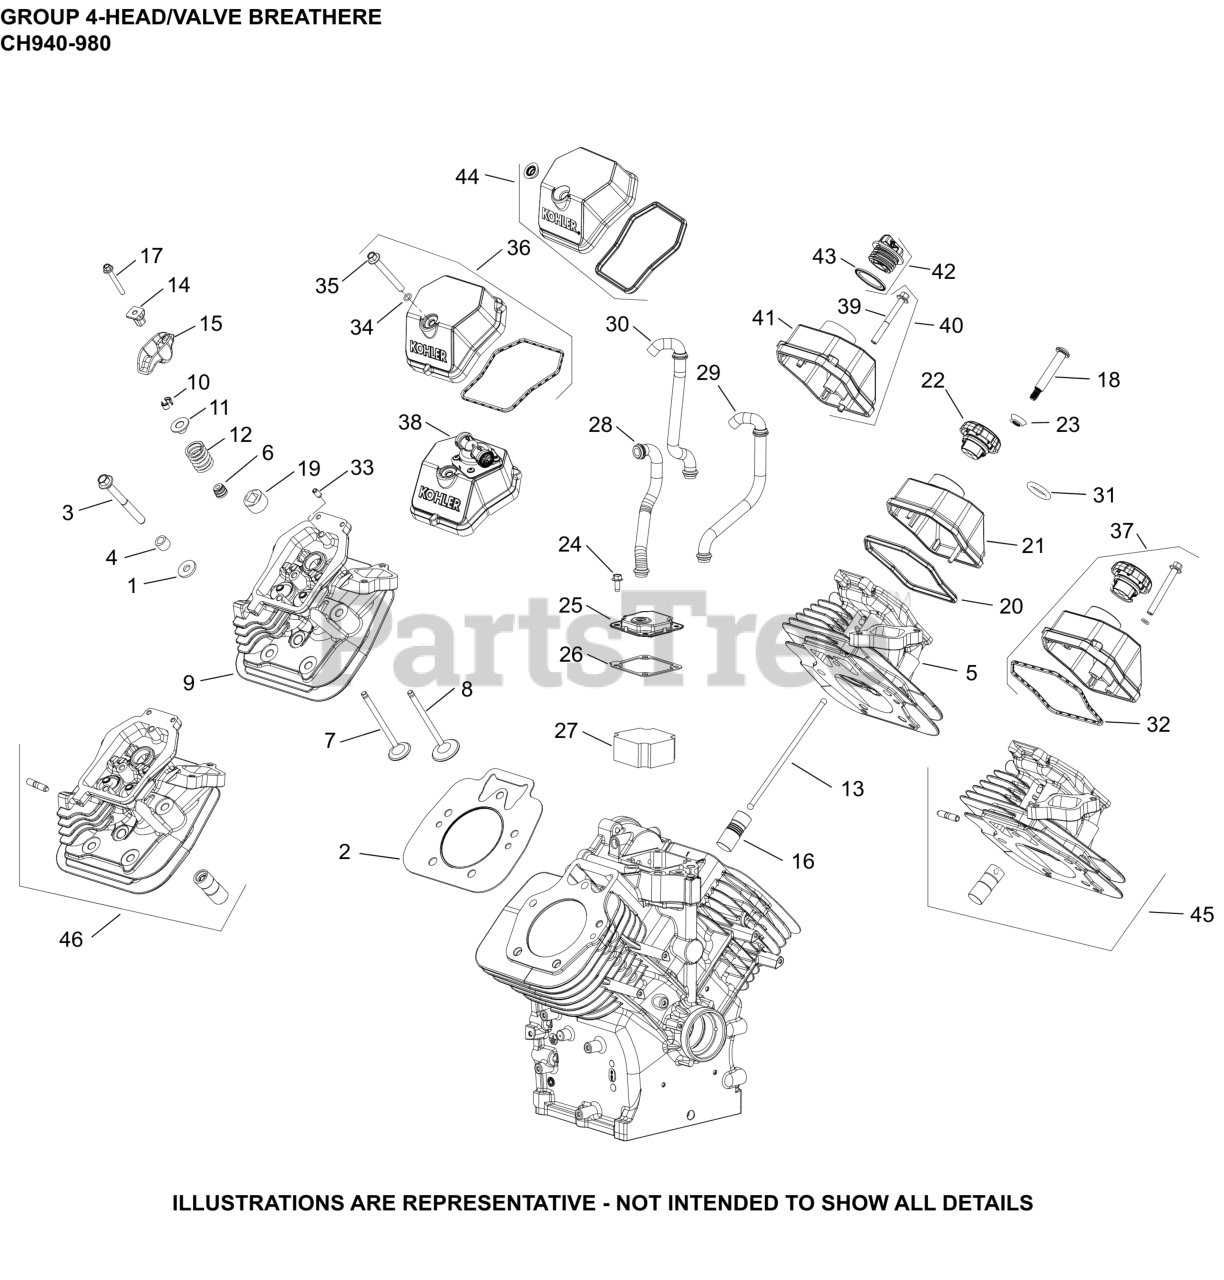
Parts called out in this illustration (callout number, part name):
1	WASHER, FLAT 13/32"
2	KIT, CYLINDER HEAD GASKET
3	SCREW, FLG M10X1.5X90
6	SEAL, VALVE BAND
7	VALVE, EXHAUST
8	VALVE, INTAKE
10	KIT, RETAINER
11	CAP, VALVE SPRING
12	SPRING, VALVE
13	ROD, PUSH
14	PIVOT, ROCKER ARM
15	ARM, ROCKER
16	LIFTER, VALVE HYDRAULIC-USE 25 351 11-S
18	SCREW, SHOULDER
19	PLUG, PIPE 3/4 NPTF SQUARE
20	SEAL, PLASTIC VALVE COVER (BLACK)
21	KIT, COVER, VALVE (OIL FILL)
22	CAP ASSEMBLY
23	GROMMET, VALVE COVER SCREW
24	SCREW, THREAD FORMING
25	KIT, BREATHER ASSEMBLY
26	GASKET, BREATHER
28	HOSE, BREATHER H/S
45	KIT, #1 CYLINDER HEAD COMPLETE
46	KIT, #2 CYLINDER HEAD COMPLETE
NI	SCREW, HEX FLANGE
NI	FILTER, BREATHER
